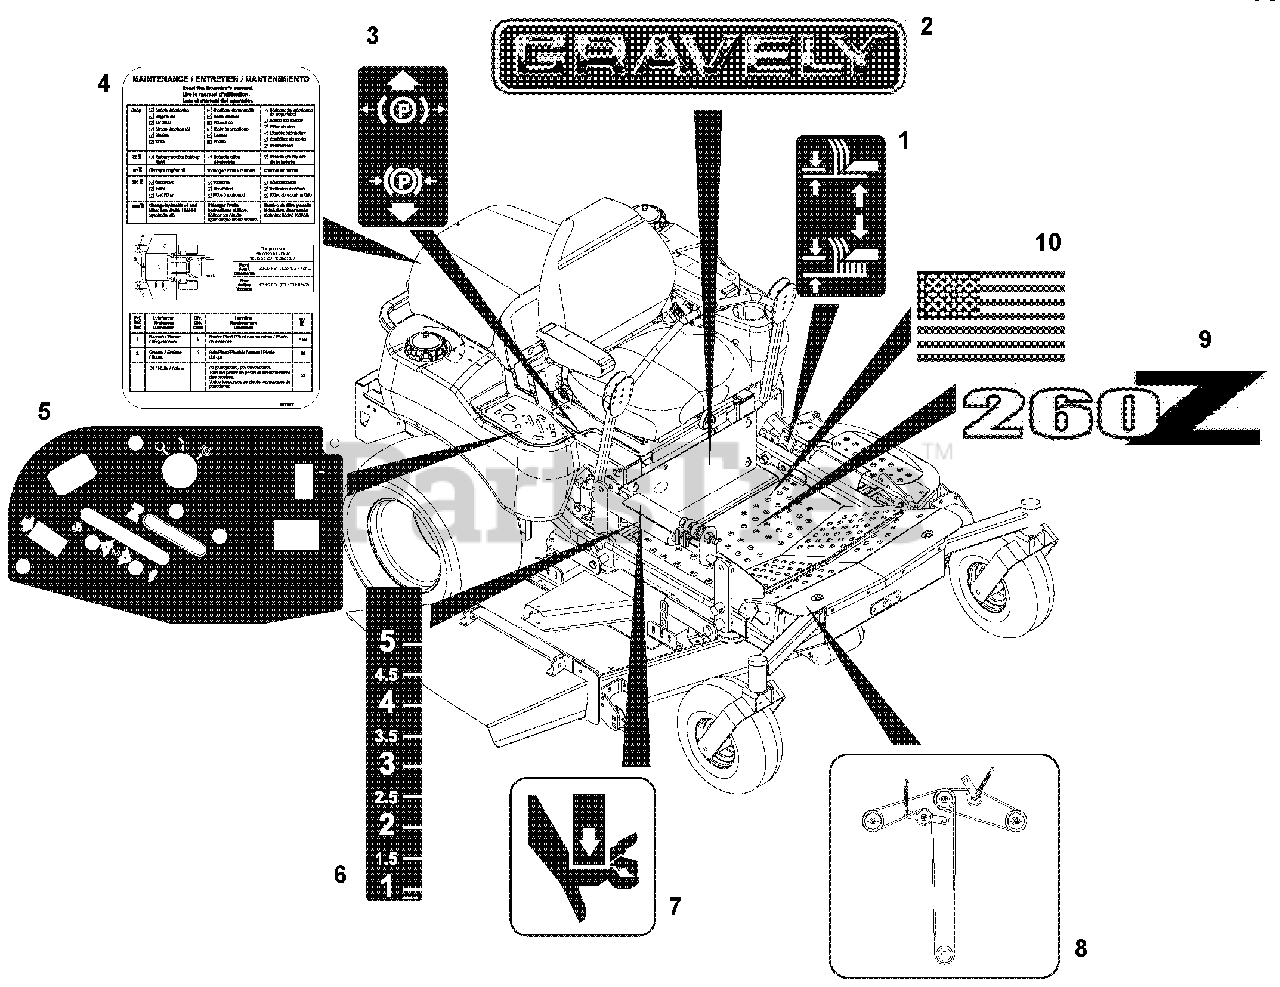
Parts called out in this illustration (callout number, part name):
1	Decal, Lift Lever (045, 046, 047, 052, 066, 067, 068, 071, 084, 085, 086, 091, 104, 106, 107, 108)
2	Decal, 15 in. Gravely Logo
3	Decal, Parking Brake Lever
4	Decal, Service Instructions
5	Decal, Control Panel (045, 046, 047, 052, 066, 067, 068, 071, 084, 085, 086, 087, 088, 089,
6	Decal, Height of Cut (045, 046, 047, 052, 066, 067, 068, 071, 084, 085, 086, 091, 104, 106,
7	Decal, Pinch Point (045, 046, 047, 052, 066, 067, 068, 071, 084, 085, 086, 091, 104, 106, 107,
8	Decal, Belt Diagram (045, 046, 047, 052, 066, 067, 068, 071, 084, 085, 086, 087, 088, 089,
9	Decal, PM-260Z (046, 047, 067, 068, 085, 088, 089, 105, 106)
10	Decal, American Flag
